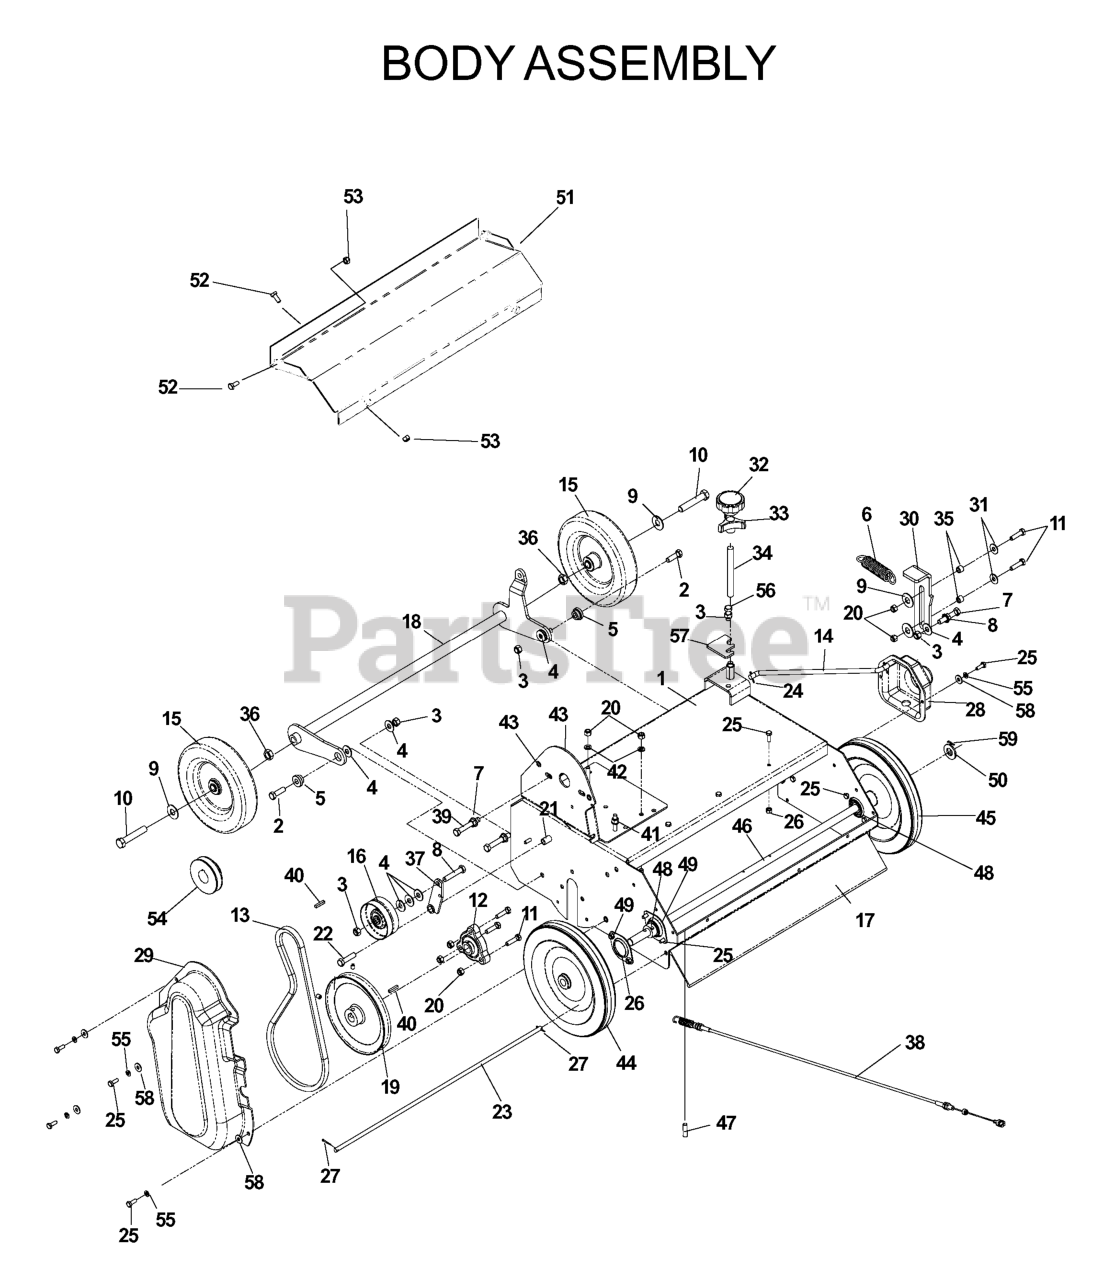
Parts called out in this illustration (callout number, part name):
1	BODY ASSEMBLY
2	HCS 3/8C X 1 1/4 GR5
3	NUT 3/8-16 NYLOC
4	WASHER 3/8 FLAT
5	BUSHING RAKE
7	NUT 3/8C WHIZ
8	HCS 3/8C X 2
9	WASHER 1/2 FLAT
10	HCS 1/2C X 2 3/4
11	HCS 5/16C X 1 1/4
12	BEARING, FLANGED
13	BELT, DRIVE RAKE/SLICER DFS
15	WHEEL 8 X 1 3/4 RAKE
16	PULLEY, IDLER RAKE & ZTR
18	FRONT AXLE
19	PULLEY W/SET SCREW
20	NUT 5/16 NYLOC
21	BEARING, ONLITE RAKE/DT
22	HCS 3/8C X 1 1/2
24	RP_COTTER PIN 1/8 X 3/4
25	HCS 1/4C X 3/4 HCS
26	NUT.1/4-20.HEX.NYLOC.ZD
27	RP_COTTER PIN 1/8 X 3/4
28	SHAFT GUARD
29	BELT GUARD
31	WASHER 5/16 FLAT
32	KNOB, BLACK THERMO PLASTIC
33	KNOB, THREE PRONG
34	THREADED ROD
36	NUT 1/2 HEX JAM
37	IDLER ARM - ORANGE
38	CABLE POWER RAKE
39	HCS 3/8C X 2 1/2
40	KEY
41	HCS 5/16C X 1 3/4
42	WASHER.LOCK.HVY.HLCL.SPR.5/16
43	BACKING PLATE ORANGE
44	WHEEL 10 X 1 3/4
45	WHEEL 10 X 1 3/4
46	AXLE, REAR
47	ROLL PIN 1/4 X 1 1/8
48	BEARING - 5/8" W/COLLAR
50	WASHER
51	REAR COVER ORANGE
52	HCS 1/4C X 5/8
53	NUT.1/4-20.HEX.NYLOC.ZD
54	ENGINE PULLEY W/SET SCW
55	LOCKWASHER 1/4"
56	HCS 3/8-16X1.GRD.5.ZD
57	DEPTH SHIM
58	WASHER 1/4 FLAT
59	COTTER PIN
60	KNURLED INSERT
